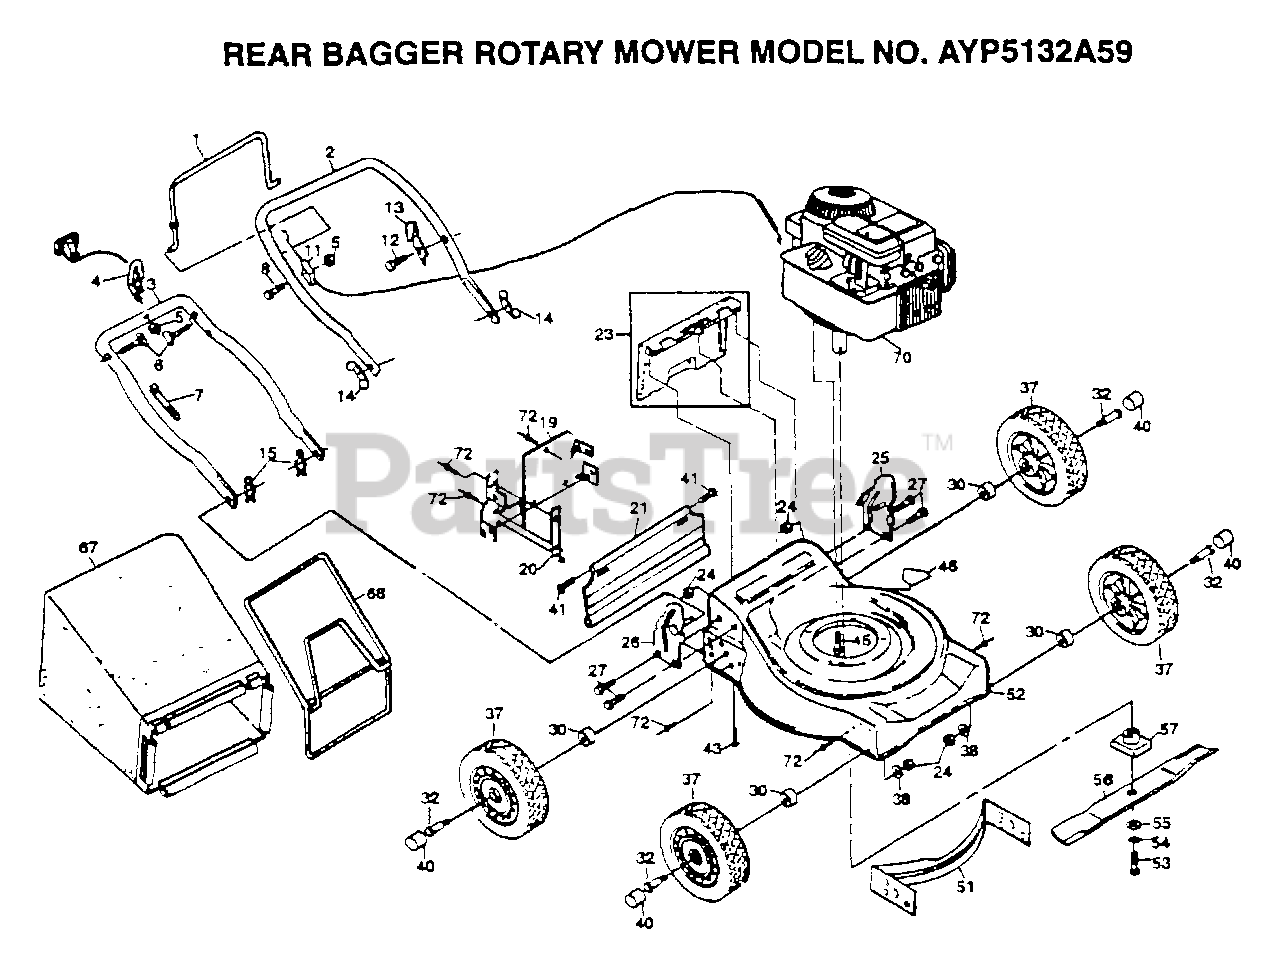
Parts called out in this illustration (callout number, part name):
1	CONTROL BAR PM
4	ROPER GUIDE PM
6	BOLT.HANDLE.LM
8	BOLT 1/4-20-1 1/2
11	"CABLE,ENG ZONE CO"
12	TAPPING SCREW
13	"BRKT,UPSTOP"
14	"NUT,WING PM"
15	HAIRPIN COTTER
19	PLATE.BACK.20RD
21	SKIRT.REAR.20RD.
23	"KIT, REAR DOOR PM"
24	LOCKNUT PM
27	SCREW
32	AXLE BOLT
37	WHEEL ASM
38	WASHER PM
40	HUB CAP-PLASTIC
41	HINGE SCREW
43	SCREW
45	SCREW
46	DECAL-DANGER PM
52	KIT.HSG.20RD
53	SCREW
54	LOCKWASHER
55	"WASHER,HARDEN"
56	BLADE.STAND.20INC
57	BLADE ADAPTOR
67	GRASS BAG
68	FRAME.CATCHER.ASM
72	BLIND RIVET
